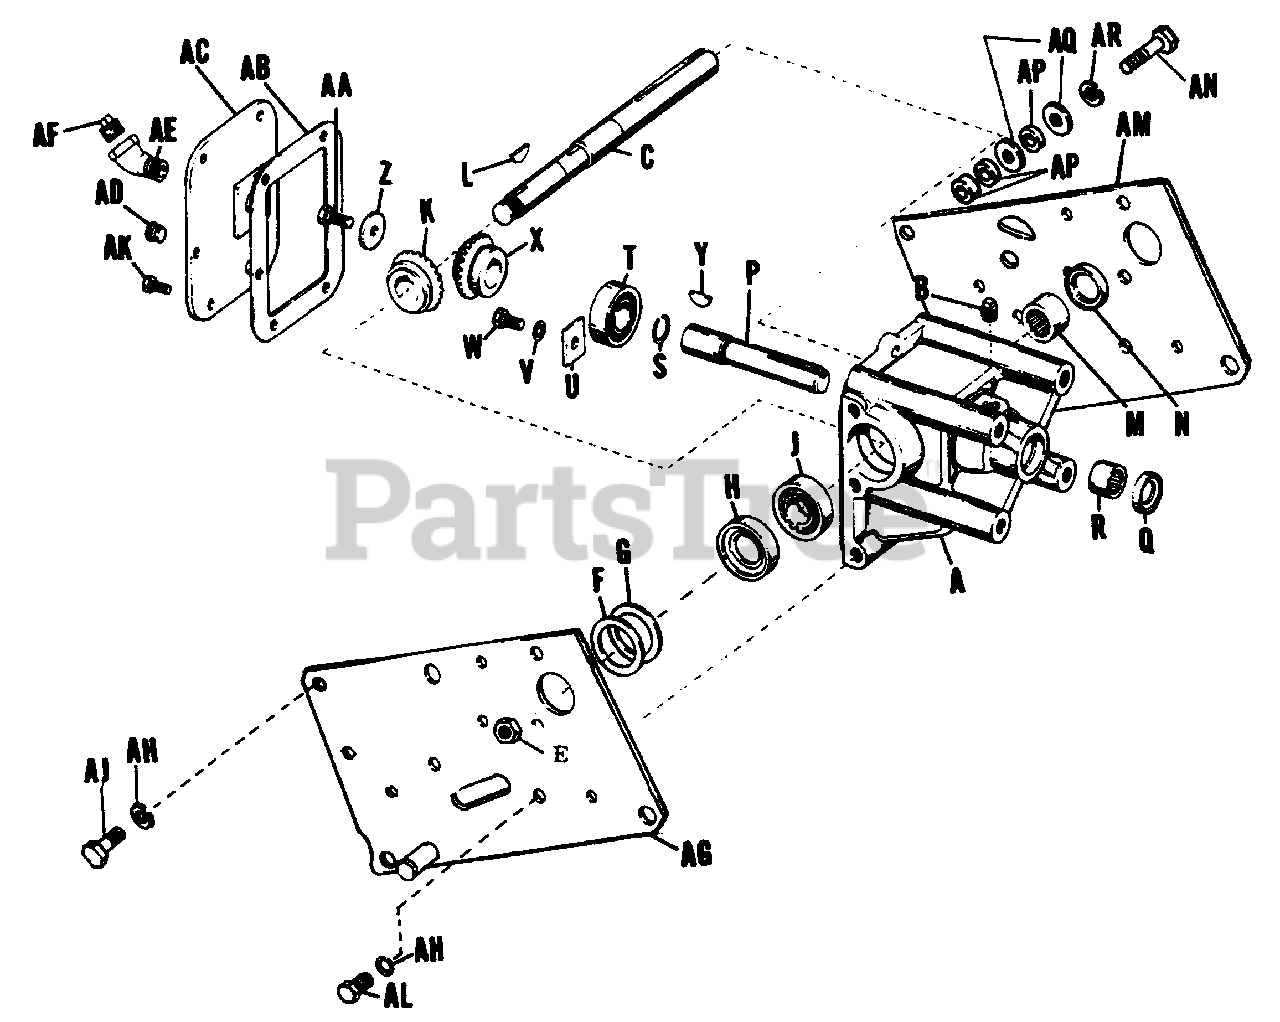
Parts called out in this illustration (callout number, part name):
A	Bevel Gear Housing, W/Bearings
B	Pipe Plug
C	Drive Shaft
E	Hex Jam Nut 3/4"-16
F	Shim (As Required)
H	Oil Seal
J	Ball Bearing
K	Bevel Driven Gear
L	Key-Woodruff
M	Needle Bearing
P	Driven Shaft
R	Needle Bearing
S	Retaining Ring
T	Ball Bearing
U	Bearing Clamp Plate
V	Lock Washer, 5/16"
W	Hex Capscrew, 5/16"-18 x 5/8" lg.
X	Bevel Driven Gear
AA	Hex Capscrew, 5/16"-18 x 3/4" lg.
AC	Housing Cover Assembly
AD	Pipe Plug
AE	Street Elbow
AF	Pipe Plug
AG	R.H. Side Plate
AH	Lock Washer, 7/16"
AJ	Hex Capscrew, 7/16"-14 x 1" lg.
AK	Hex Capscrew, 1/4"-20 x 5/8" lg.
AL	Hex Capscrew, 7/16"-14 x 1-1/4" lg.
AM	L.H. Side Plate
AN	Hex Capscrew, 7/16"-14 x 2" lg.
AQ	Washer, 7/16"
AR	Lock Washer, 7/16"
